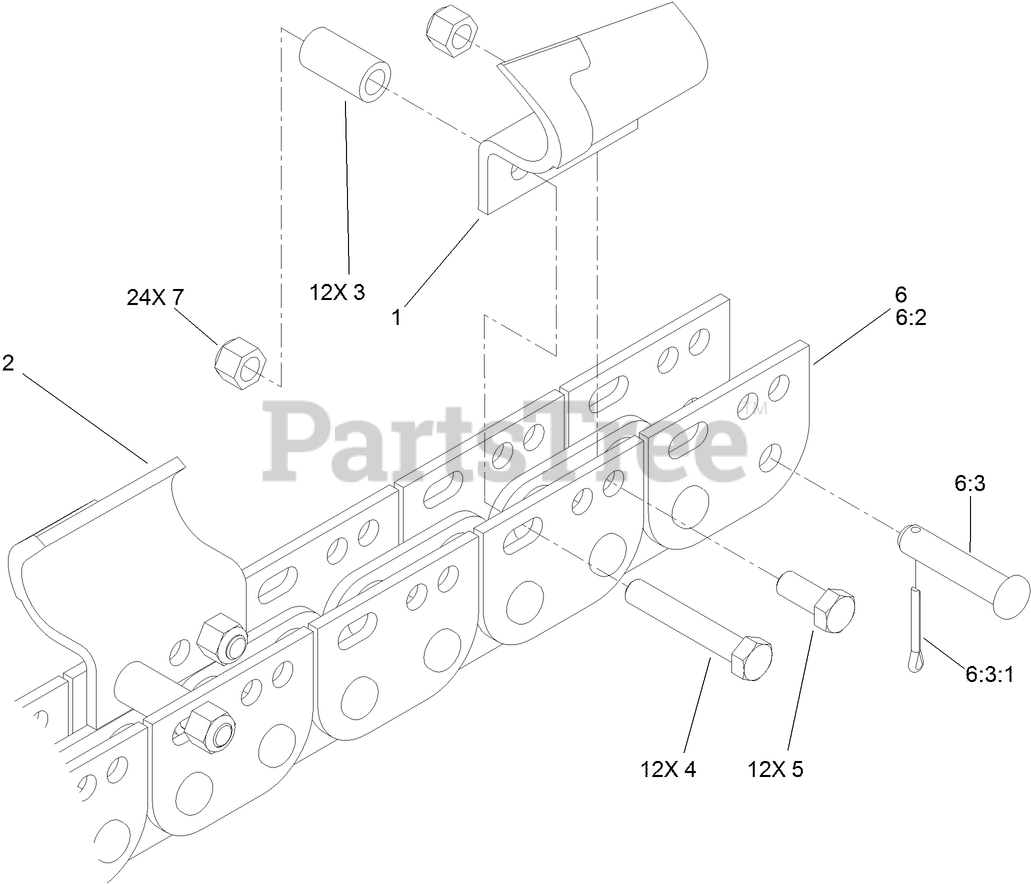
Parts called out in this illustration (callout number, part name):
1	TOOTH-SOIL, LH
2	TOOTH-SOIL, RH
3	SPACER-TUBE
4	SCREW-HH
6	CHAIN-BARE, 24 STATION
6:2	LINK REPAIR KIT
6:3	PIN-CONNECTING (61MM)
6:3:1	PIN-COTTER
7	NUT-HEX
